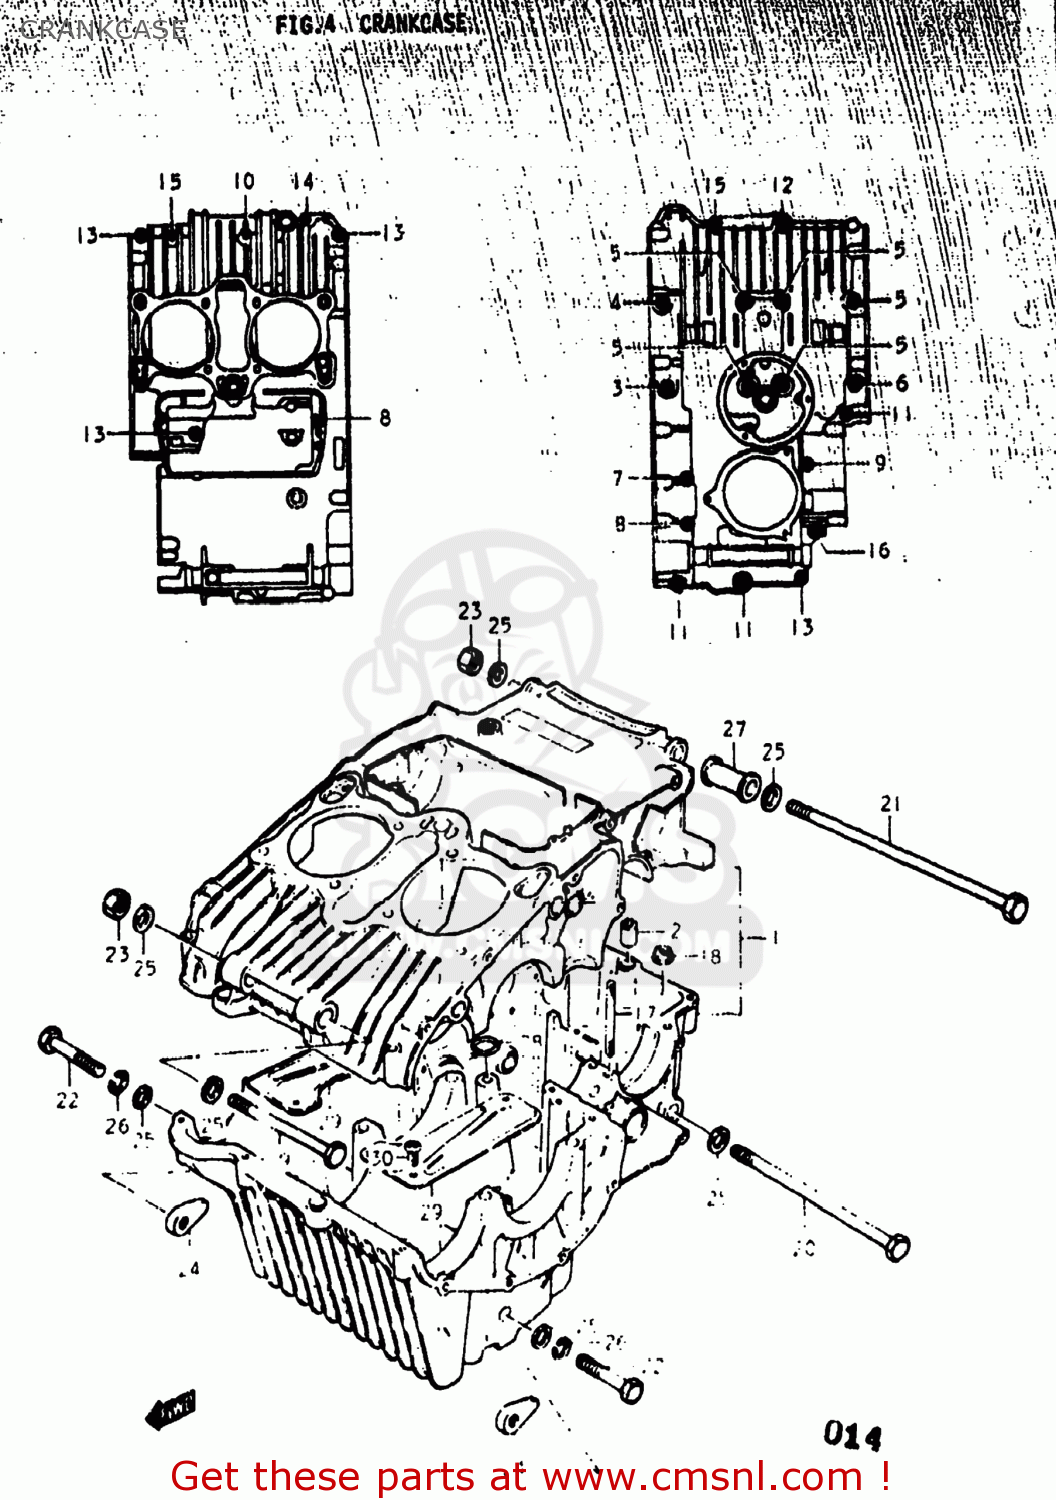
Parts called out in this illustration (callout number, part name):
1	CRANKCASE SET
2	PIN
3	BOLT
4	BOLT
5	BOLT
6	BOLT
7	BOLT
8	BOLT
9	BOLT
10	BOLT
11	BOLT
12	BOLT
13	BOLT
14	BOLT
15	BOLT
16	BOLT
17	STUD BOLT
18	NUT
19	BOLT
20	BOLT 10X160
21	BOLT 10X265
22	BOLT
23	NUT
24	NUT
25	WASHER
26	LOCK WASHER
27	SPACER
28	O-RING
29	PLATE,OIL SEPARATOR
30	SCREW 6X12
